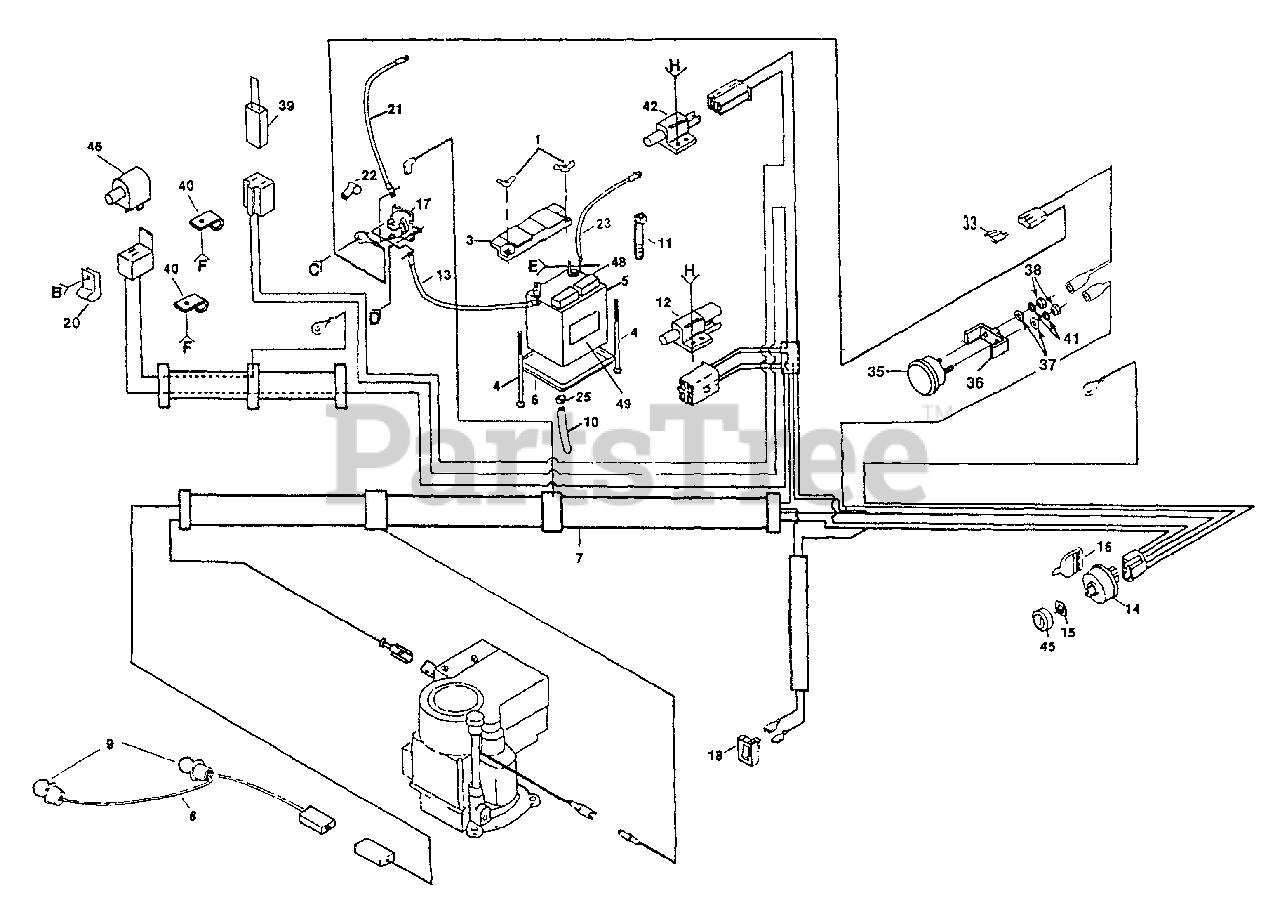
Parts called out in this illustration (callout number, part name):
1	Wing Nut 1/4 - 20
3	Terminal Guard
4	Carriage Bolt 1/4 - 20 x 7-1/2
5	Battery 12V.
6	Battery Tray
7	Ignition Harness
8	Harness, Light Socket
9	Light Bulb
10	Tube, Battery Tray
11	Cable Tie
12	Switch, Interlock, Attachment Clutch
13	Cable, Battery
14	Switch, Ignition
15	Nut, Ignition
17	Solenoid
18	Switch, Light
20	Clip Wire
21	Cable, Battery
22	Terminal Cover
23	Cable, Battery
25	Clamp, Hose
33	Fuse, 30 AMP
36	Bracket, Ammeter
37	Washer, 7/32 x 1/2 x 18 Ga.
39	Loop, Wire
40	Clip, Insulated
41	Washer, Lock Ext. 3/4
42	Switch, Interlock, Clutch Pedal
45	Bezel, Ignition
46	Switch, Plunger
48	Battery Caps Set
49	Decal, Battery Caution
